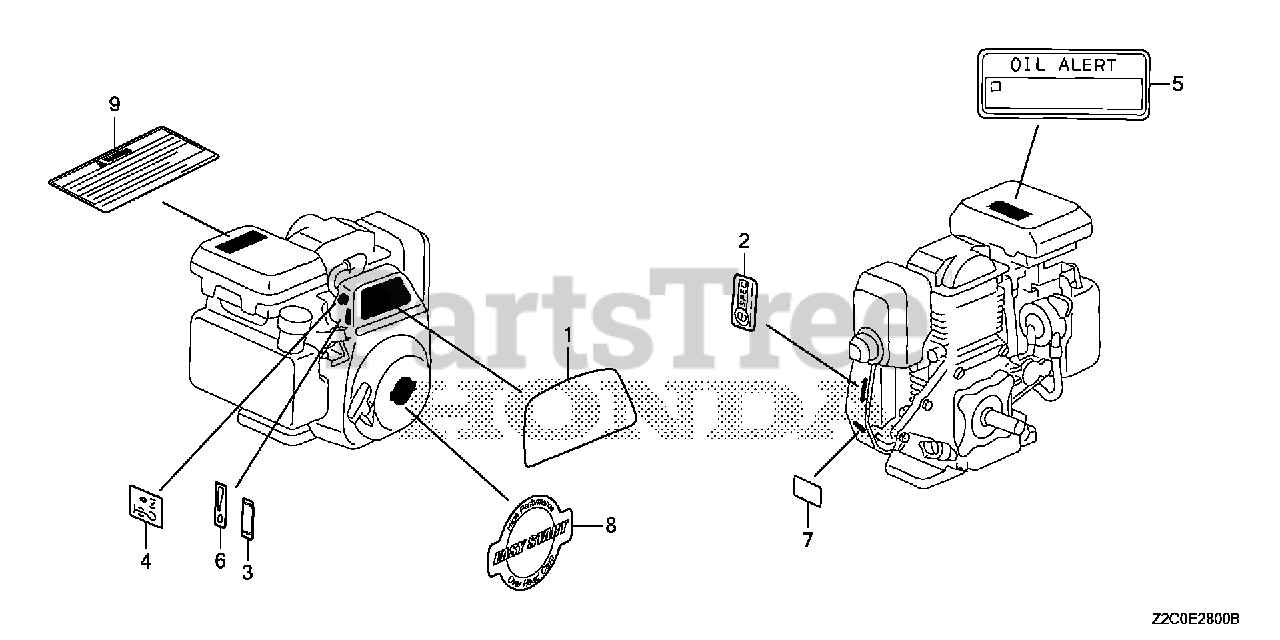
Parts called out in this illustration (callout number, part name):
1	MARK, EMBLEM (GS190)
4	MARK, CHOKE
7	LABEL, WARNING (NOT CERTIFIED FOR SALE)
8	MARK, RECOIL COVER
9	MARK, OPERATOR CAUTION (ENGLISH)
